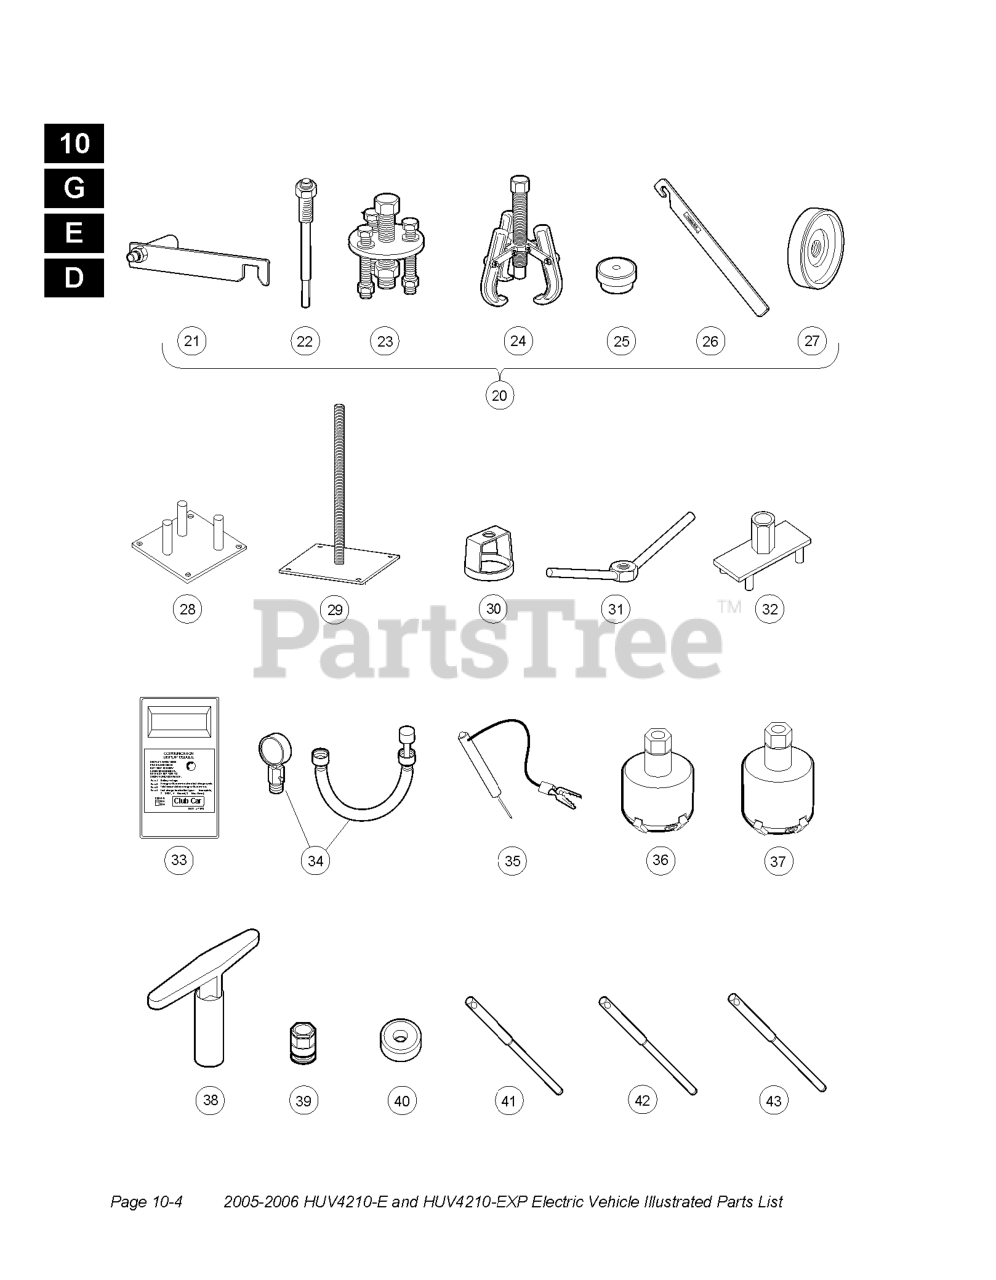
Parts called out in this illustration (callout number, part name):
28	TOOL-STATIONARY PRIMARY
33	COMMUNICATION DISPLAY MODULE
35	CONTINUITY TESTER
